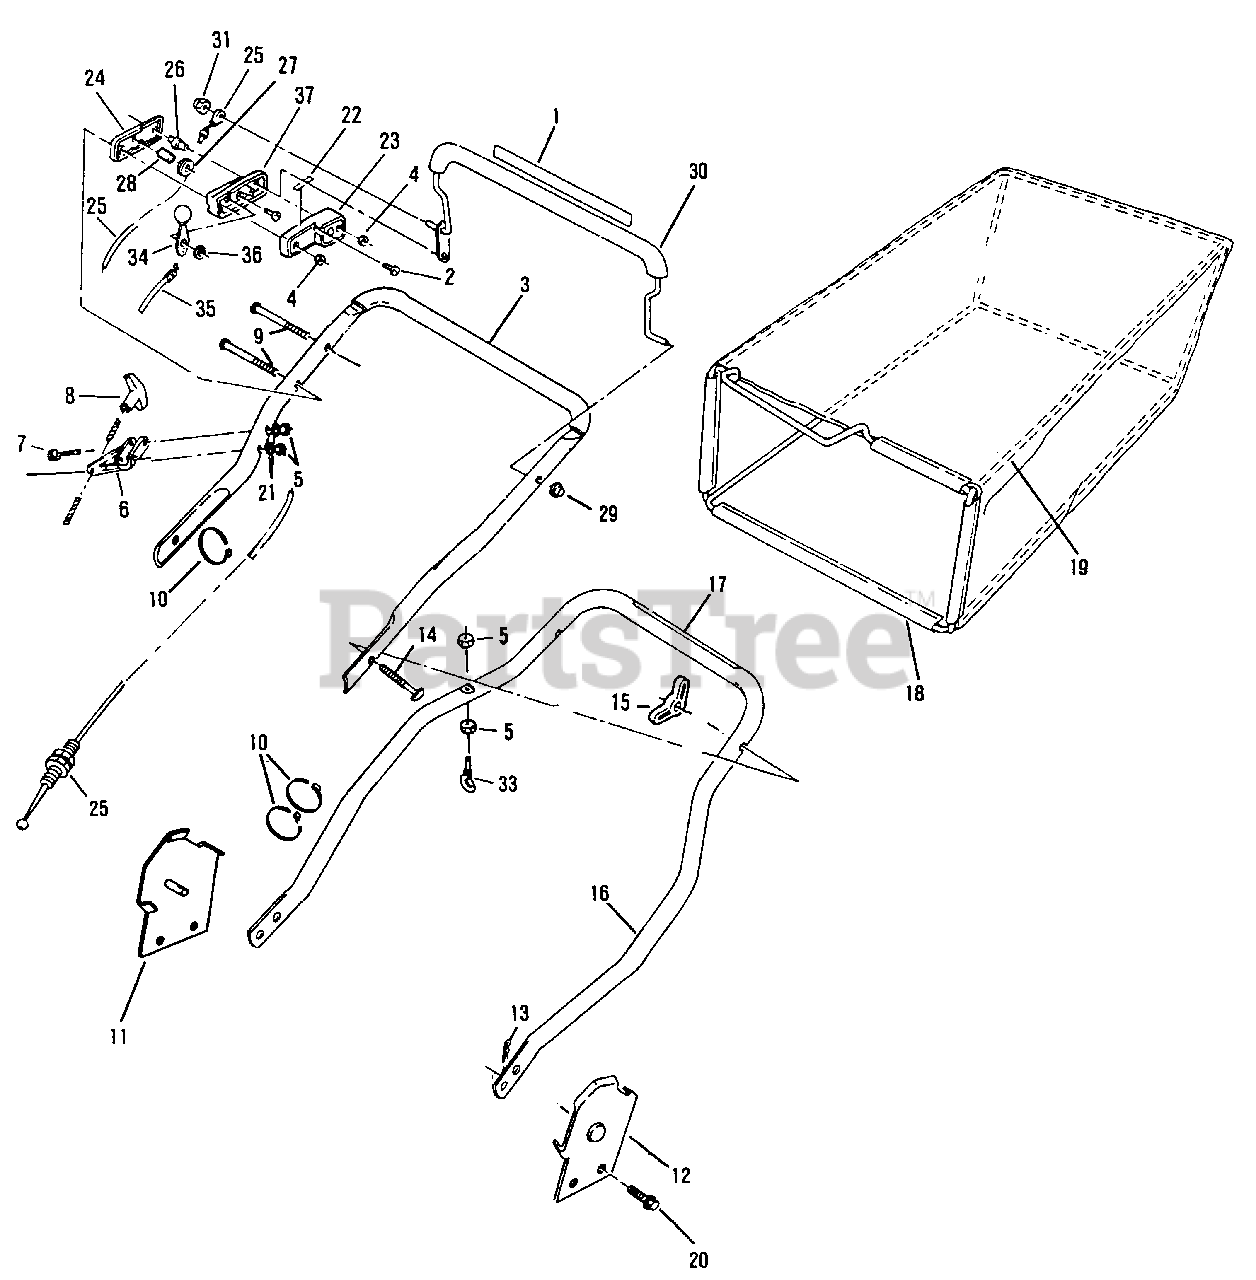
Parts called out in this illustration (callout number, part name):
1	Decal-Engine/Blade Control
2	Screw Truss Head
3	Top Handle
4	Locknut-Hex
5	Locknut
6	Rope Guide Assembly
7	Screw-Truss Head
8	Handle-Starter
9	Screw
10	Tie Strap
11	Bracket-Handle-R.H.
12	Bracket-Handle-L.H.
13	Hair Pin
14	Screw
15	Knob
16	Handle-Bottom
17	Decal-Starting Instructions
18	Bag Assembly
19	Frame-Support Bag
20	Screw-Bracket Handle to Housing
21	Washer
22	Decal-Throttle
23	Control Case-Inner
24	Control Case-Outer
25	Control Cable Assembly
26	Column
27	Pulley
28	Pin
29	Pushnut
30	Control Lever and Nut Assembly
31	Nut-Acorn
33	Eyebolt
34	Lever and Knob
35	Cable-Throttle
36	Washer-Spring
37	Case-Throttle-Center
